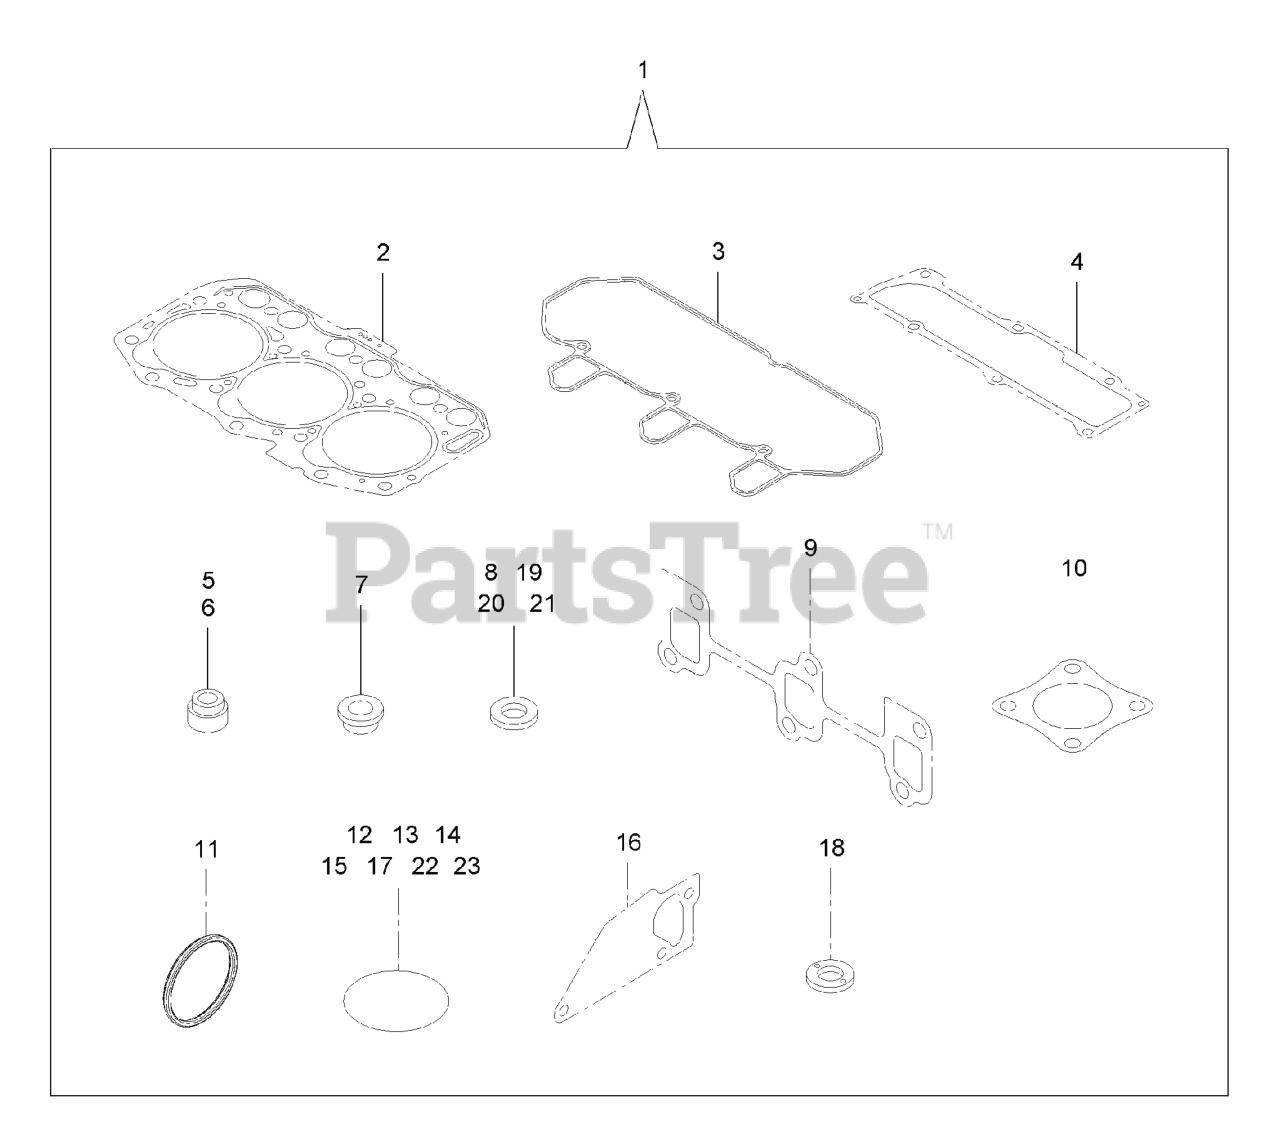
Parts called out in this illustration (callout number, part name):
1	GASKET KIT
2	GASKET SET-HEAD
3	GASKET-BONNET
5	SEAL-STEM, VALVE
6	SEAL-STEM, VALVE
7	PROTECTOR-NOZZLE
8	GASKET-NOZZLE
9	GASKET-EXH MANIFOLD
10	GASKET-SILENCER
11	GASKET-WASHER
16	GASKET-WATER PUMP
19	WASHER-SEAL
20	WASHER-SEAL
